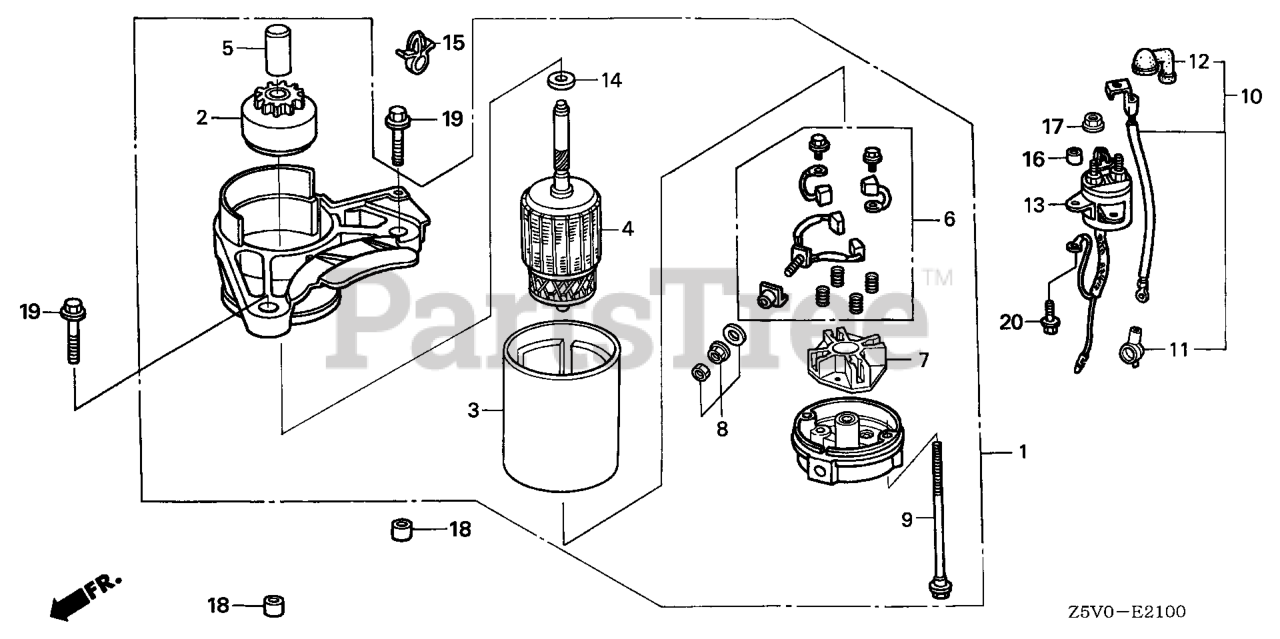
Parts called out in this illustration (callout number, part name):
1	MOTOR ASSY., STARTER
2	DRIVE ASSY.
5	STOPPER SET, PINION
6	BRUSH SET
7	HOLDER, BRUSH
8	NUT SET, TERMINAL
9	BOLT, THROUGH
10	WIRE, MAGNETIC SWITCH
11	COVER, STARTER TERMINAL
12	COVER, MAGNETIC SWITCH TERMINAL
13	SWITCH ASSY., STARTER MAGNETIC
14	WASHER, THRUST
16	COLLAR (6.5X11X10)
16	COLLAR, DISTANCE
17	NUT-WASHER (6MM)
18	PIN, DOWEL (10X12)
19	BOLT, FLANGE (8X35)
20	BOLT, FLANGE (6X25)
